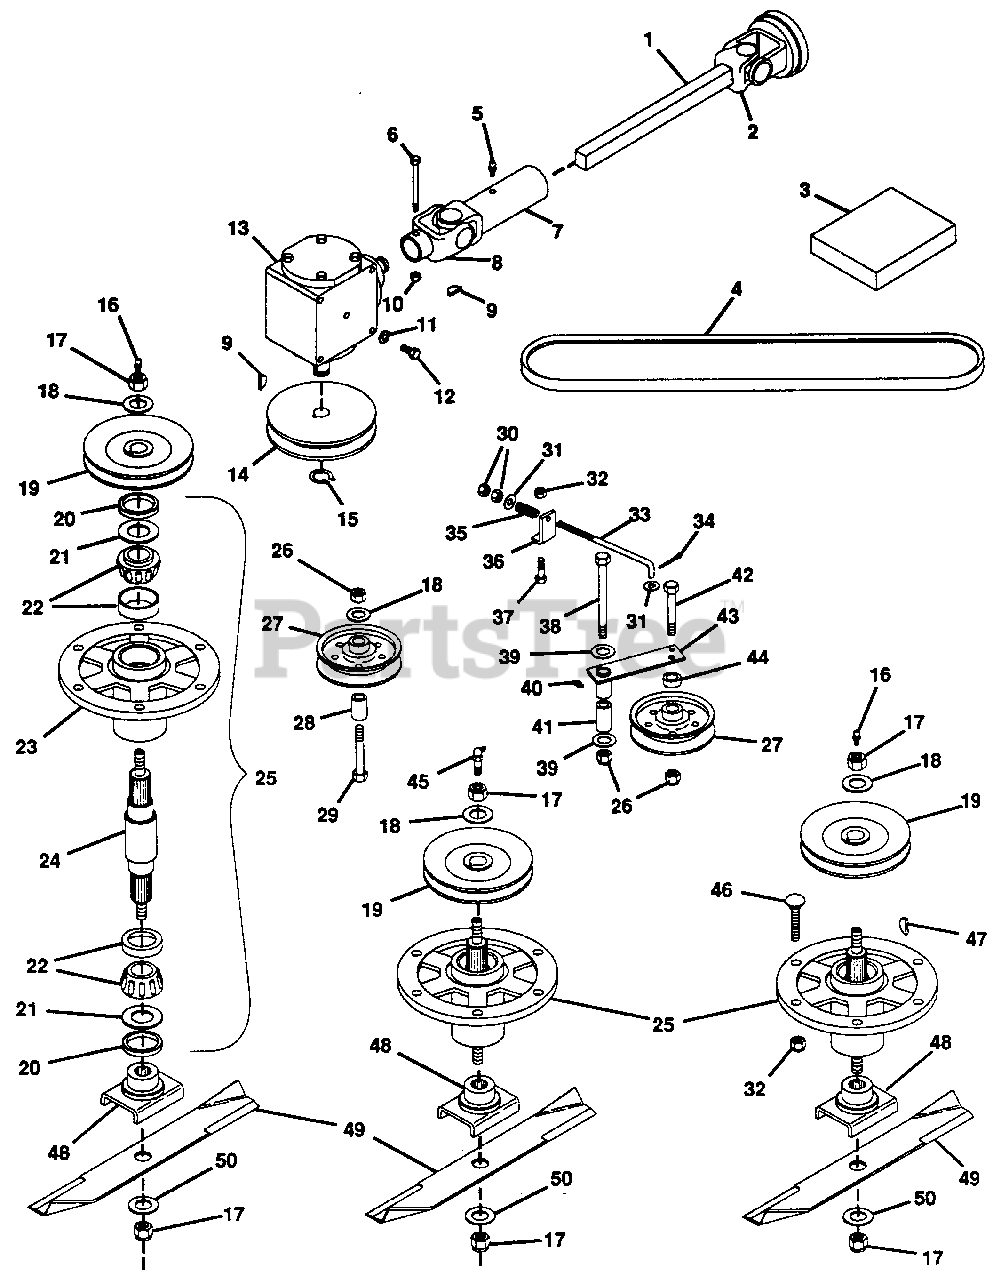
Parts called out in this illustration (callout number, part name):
1	U-Joint, Male End
2	Yoke
3	Kit, Repair U-Joint
4	Belt, Vee 72" Mower
5	Fitting, Lube 1/4-28
6	Bolt, Hex 5/16-18x2.25
7	Assembly, U-Joint
8	Yoke
9	Key, Woodruff .25x.875 Hard #A
10	Nut, Lock 5/16-18
11	Washer, Lock 3/8 Reg.
12	Bolt, Hex 3/8-16x.875
13	Gearbox, 72" Mower
14	Sheave, Gear Box
15	Ring, Retaining .875 Shaft
16	Fitting, Lube 1/8
17	Nut, Lock 5/8-11
18	Washer, Flat .687x1.312x.122
19	Weldment, Spindle Sheave
20	Seal, Steel
21	Washer, Flat .975x1.970x.030
22	Assembly, Bearing
23	Housing, Bearing
24	Shaft, Spindle
25	Assembly, Spindle
26	Nut, Lock 1/2-13
27	Pulley, Flat Idler
28	Spacer, .516x.875x.300
29	Bolt, Hex 1/2-13x2.00
30	Nut, Hex 3/8-24
31	Washer, Flat .406x.812x.065
32	Nut, Lock 3/8-16
33	Rod, Idler
34	Pin, Cotter .094x.75
35	Spring, Comp. 1x.78x338
36	Support, Spring "B"
37	Bolt, Hex 3/8-16x1.00
38	Bolt, Hex 1/2-13x3.75
39	Washer, Flat .500x1.250x.083
40	Fitting, Lube 1/4-28
41	Spacer, .850x.546x2.50
42	Bolt, Hex 1/2-13x2.75
43	Weldment, Idler Pivot
44	Spacer, Idler Pulley
45	Fitting, Lube 65 Degree
46	Bolt, 3/8-16x1.375 Rd Hd Sq Nk
47	Key, Woodruff .25x1.00 Hard #15
48	Weldment, Blade Cradle
49	Blade
50	Washer, Flat .656x1.312x.095
